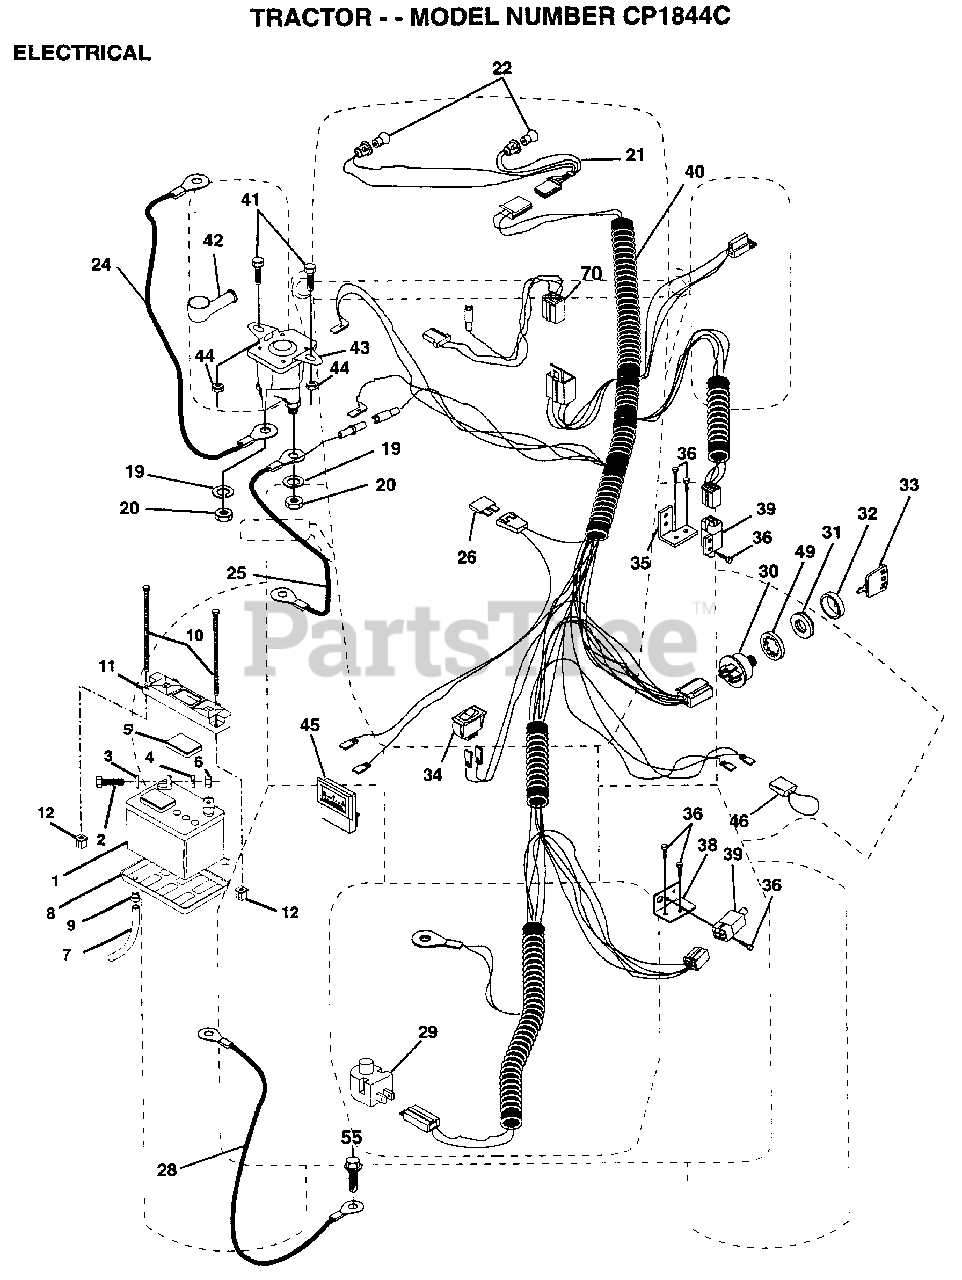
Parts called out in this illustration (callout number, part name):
2	BOLT LT
3	WASHER
4	LOCKWASHER
5	"CAP,BATTERY "
7	"DRAIN TU T, BATT"
8	"TRAY T, BATTERY"
9	HOSE CLAMP T
20	NUT
21	"HARNESS,LIGHT SOC"
22	HEADLAMP BULB
24	"CABLE T, BATTERY"
25	CABLE.6GA.22W/16W
26	FUSE HYT
28	CABLE.GRND.6GA.21
29	SWITCH SEAT
32	COVER KEY SWITCH
33	KEY MLD GEN DELTA
34	SWITCH LT
35	BRACKET LT
36	SCREW
38	BRACKET SWITCH IN
39	SWITCH INTERLOCKT
40	HARNESS.IGN.MECH.
41	BOLT HXHD FIN
44	NUT HXKEP 1/4X20
46	PROTECTION LOOP
49	LOCKWASHER
55	SCREW LT
70	HARNESS ENG DUAL
